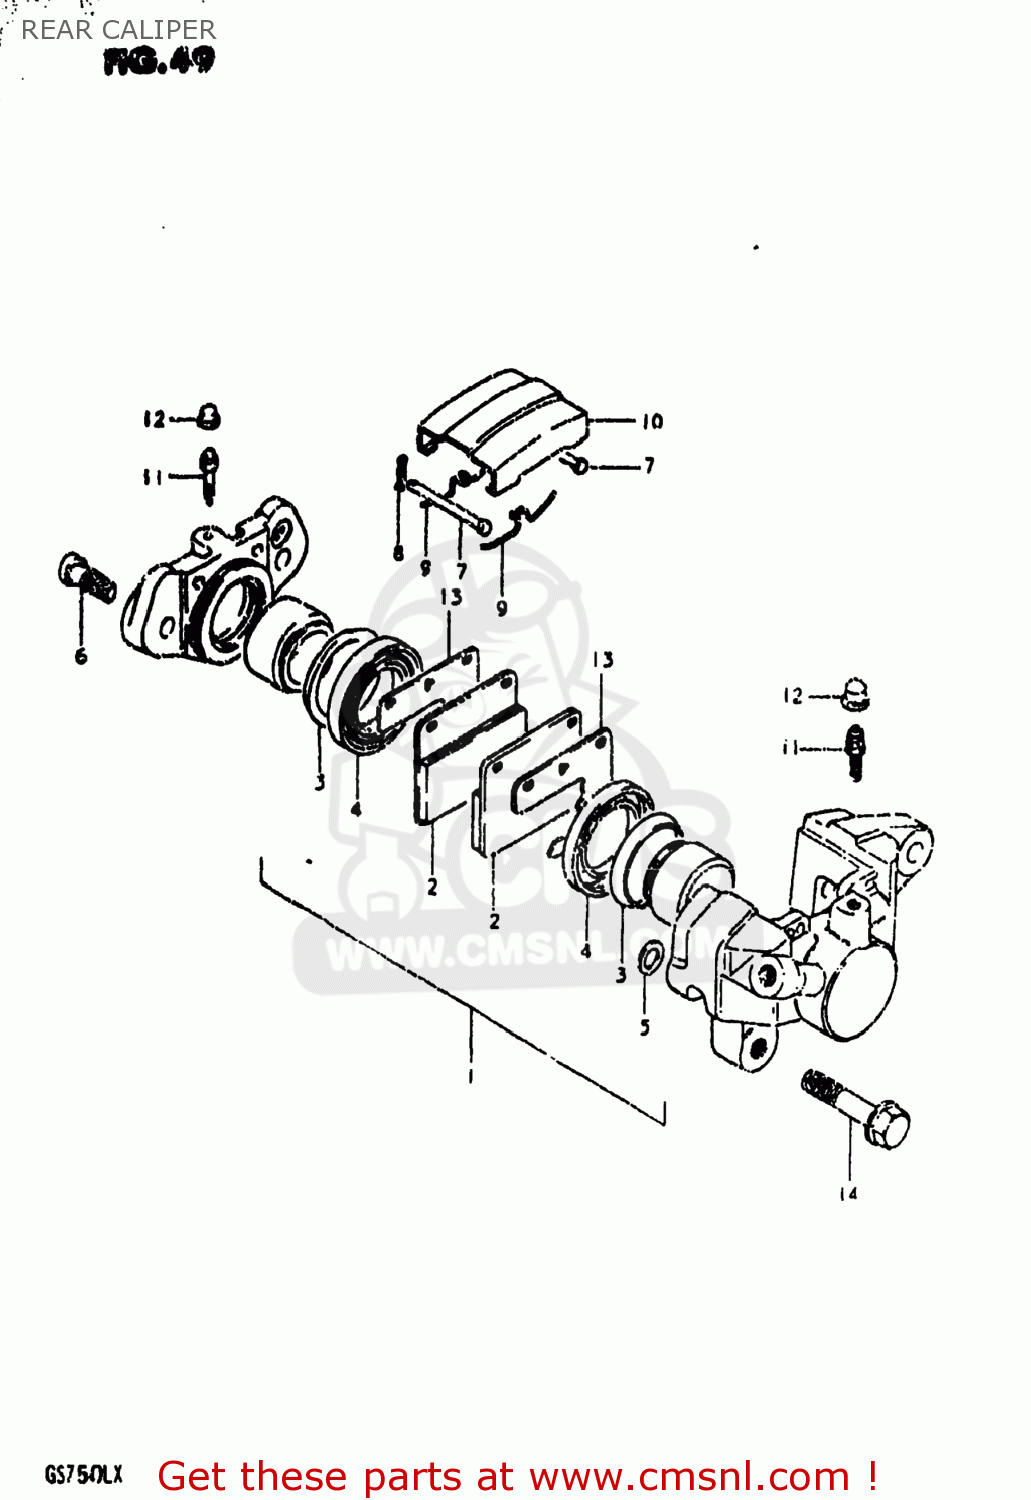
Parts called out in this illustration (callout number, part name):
1	PISTON SET
2	PAD,BRAKE
3	SEAL,PISTON
4	BOOT,PISTON
5	SEAL,PISTON
6	BOLT,HOUSING
7	PIN,PAD
8	CLIP,PAD PIN
9	SPRING
10	COVER,DUST
11	BLEEDER
12	CAP,BREATHER
13	SHIM,RR CALIPER
14	BOLT
